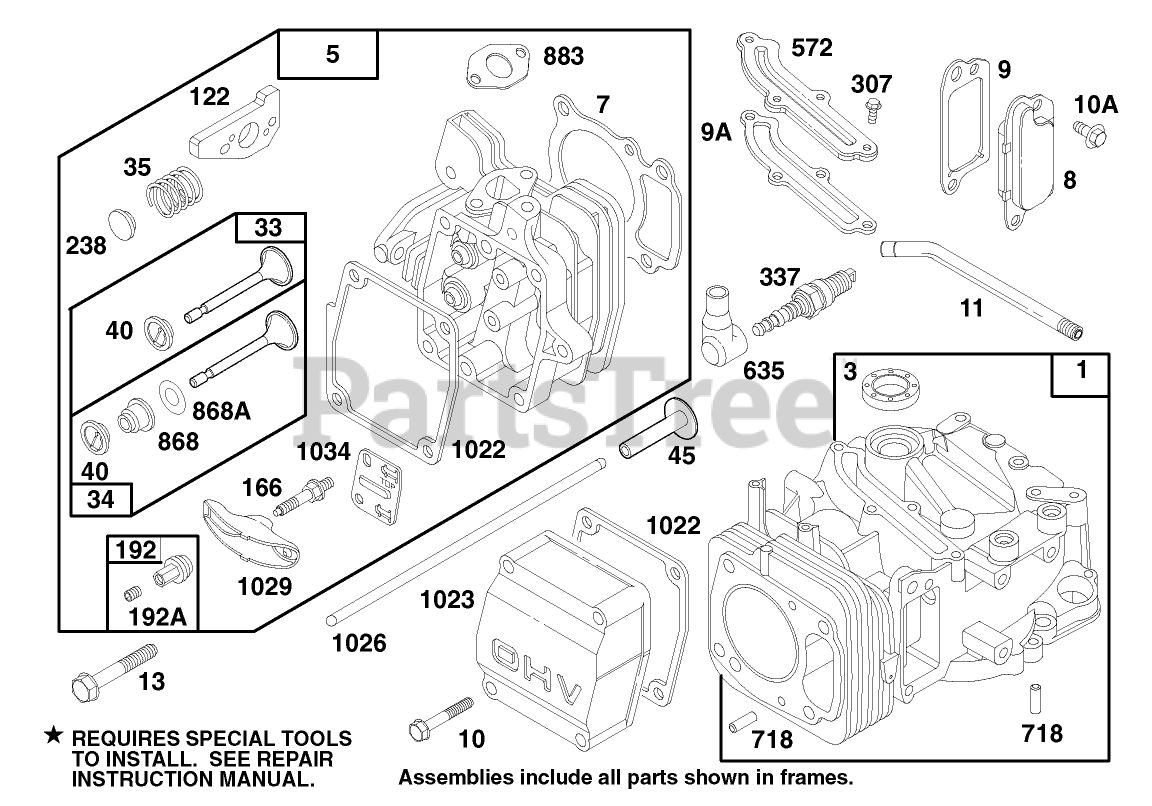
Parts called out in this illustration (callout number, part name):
98A	SPEED ADJUST. SCREW ASM
163	AIR CLEANER GASKET
188	SCREW - HEX HEAD
201	GOVERNOR LINK
209	GOVERNOR SPRING
529	BREATHER TUBE
535	FILTER ELEMENT
618	RETURN SPRING
620	CARBURETOR BRACKET
621	STOP SWITCH
966	AIR CLEANER BASE
968	AIR CLEANER COVER
969	AIR CLEANER SCREW
971	AIR CLEANER SCREW
